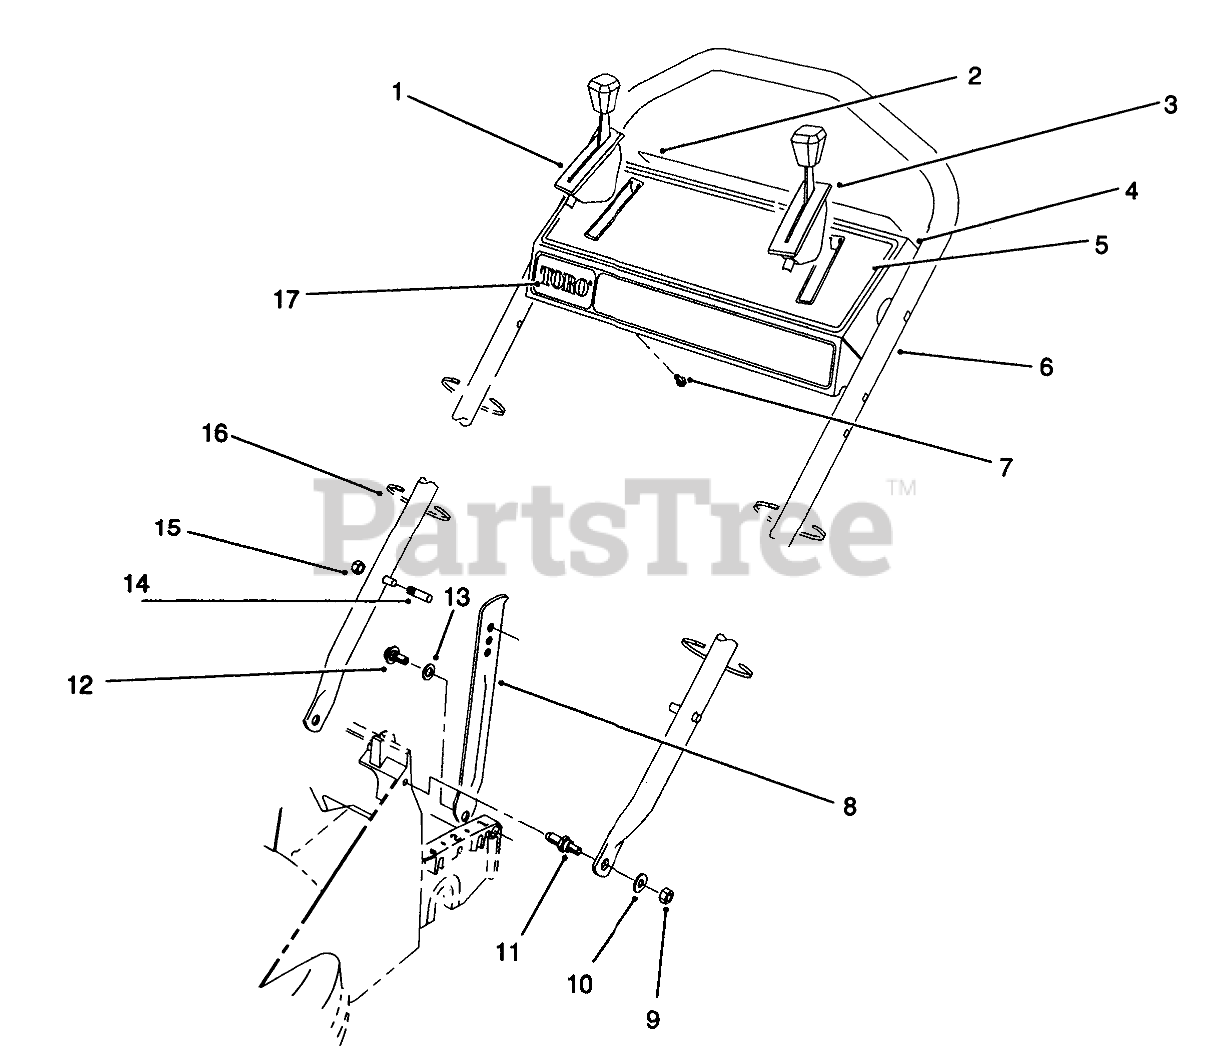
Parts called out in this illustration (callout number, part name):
1	Control-Ground Speed
2	DECAL - PANEL, REAR
3	THROTTLE CONTROL
4	Control Panel Assembly (Incl. Ref. #2, 5 & 17)
5	DECAL - INSTRUCTION
6	UPPER HANDLE, PVC DIP
7	SCREW-HWHTF
8	HANDLE LATCH
9	NUT-LOCK, NI
10	WASHER-PLAIN
11	SCREW - SHOULDER STUD
12	SCREW-SHOULDER
13	NYLON WASHER
14	HANDLE PIN
15	Net-Lock
16	TIE-CABLE
17	DECAL - TORO PANEL
